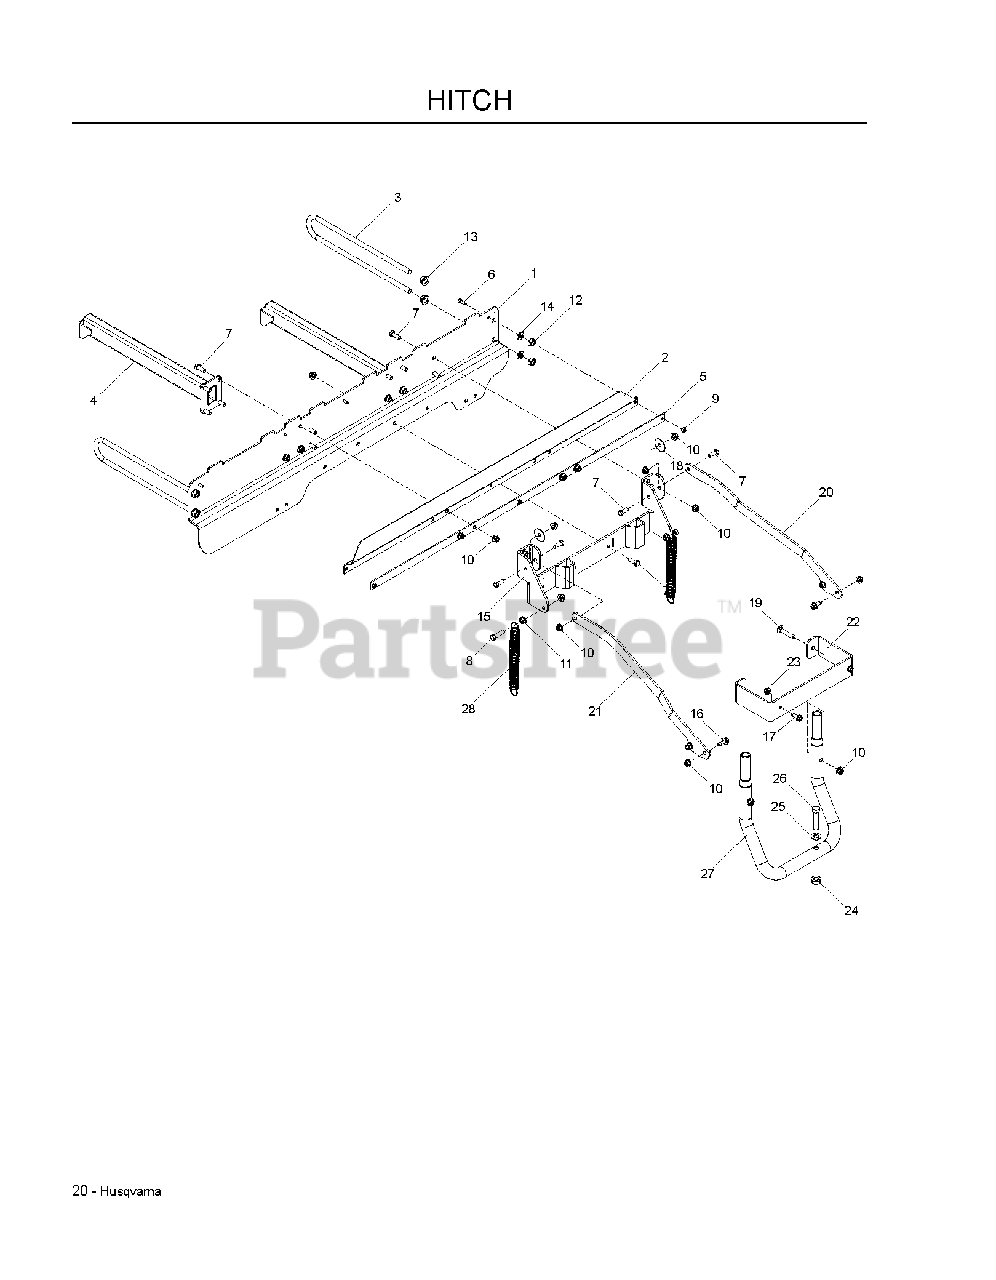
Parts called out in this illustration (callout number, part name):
1	MOUNT Z BRACE
2	SEAL, RUBBER
3	SUPPORT, OUTER
4	SUPPORT ARM WELDMENT
5	SEAL STRAP
6	HCS 1/4C X 3/4 HCS
7	HCS 3/8C X 1
8	HCS 3/8C X 1 1/2
9	NUT 1/4-20 NYLOC
10	NUT 3/8-16 HEX FLG NYLOC ZD
11	NUT 3/8C WHIZ
12	NUT 1/2 HEX JAM
13	NUT 1/2-13 HEX
14	WASHER 1/2" SPLIT LOCK
15	MOUNT, HITCH, BLK
16	BOLT 3/8-16 X 1.0
19	RHSNB 3/8C X 2
20	STRAP, RT, BLK
21	STRAP, LT, BLK
22	BRACKET, SUPPORT, BLK
23	5/16-18 NYLOC FLANGE NUT
24	NUT, 1/2-13 HEX FLG NYLOC ZD
25	WASHER 1/2" FLAT
26	HEX SCREW-.5C X 2.25
27	TUBE, HITCH, BLK
